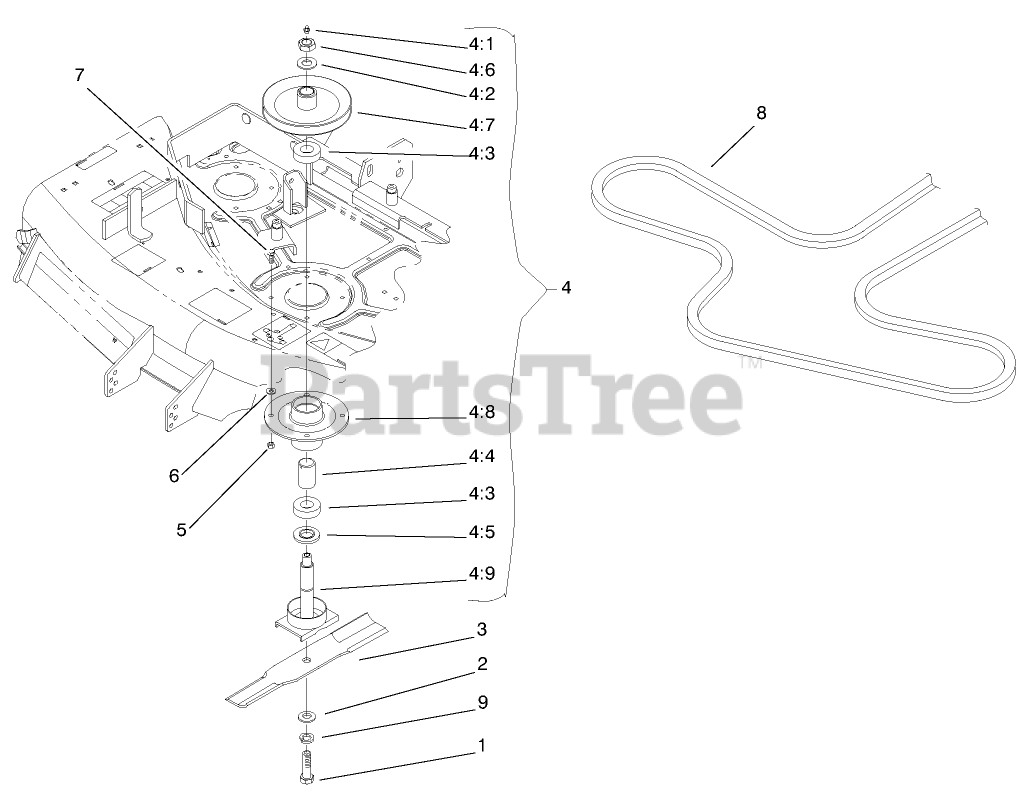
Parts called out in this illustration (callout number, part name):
1	SCREW-BLADE
2	WASHER-FLAT
3	Blade
4	Spindle Housing ASM
4:1	FITTING-GREASE
4:2	WASHER
4:3	BEARING-BALL
4:4	SPACER-BEARING
4:5	SPACER-SPINDLE
4:6	NUT-HEX
4:7	PULLEY ASM
4:8	HOUSING-SPINDLE
4:9	SPINDLE SHAFT ASM
5	7/8X046 IN SNAP RING
6	WASHER-FLAT
7	SCREW-HH
8	V-BELT, DRIVE
9	WASHER-LOCK
